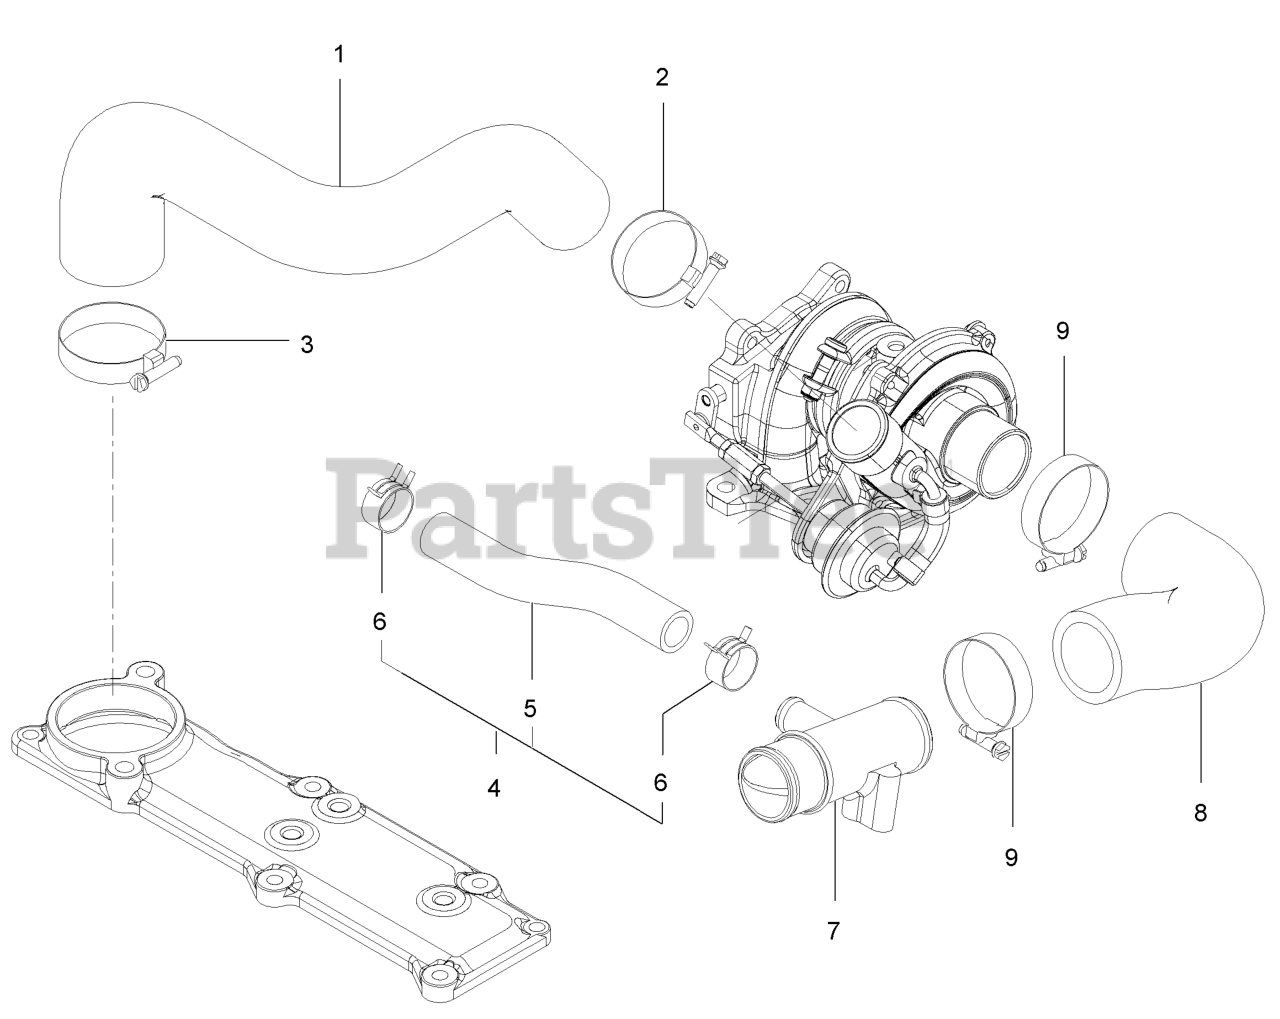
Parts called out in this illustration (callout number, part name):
1	Hose-Air Intake
2	Clamp-Hose
3	Clamp-Hose
4	Hose ASM-Breather
5	Hose-Breather
6	Clip-Hose
7	Joint-Breather
8	Hose-Air Intake
9	Clamp-Hose
